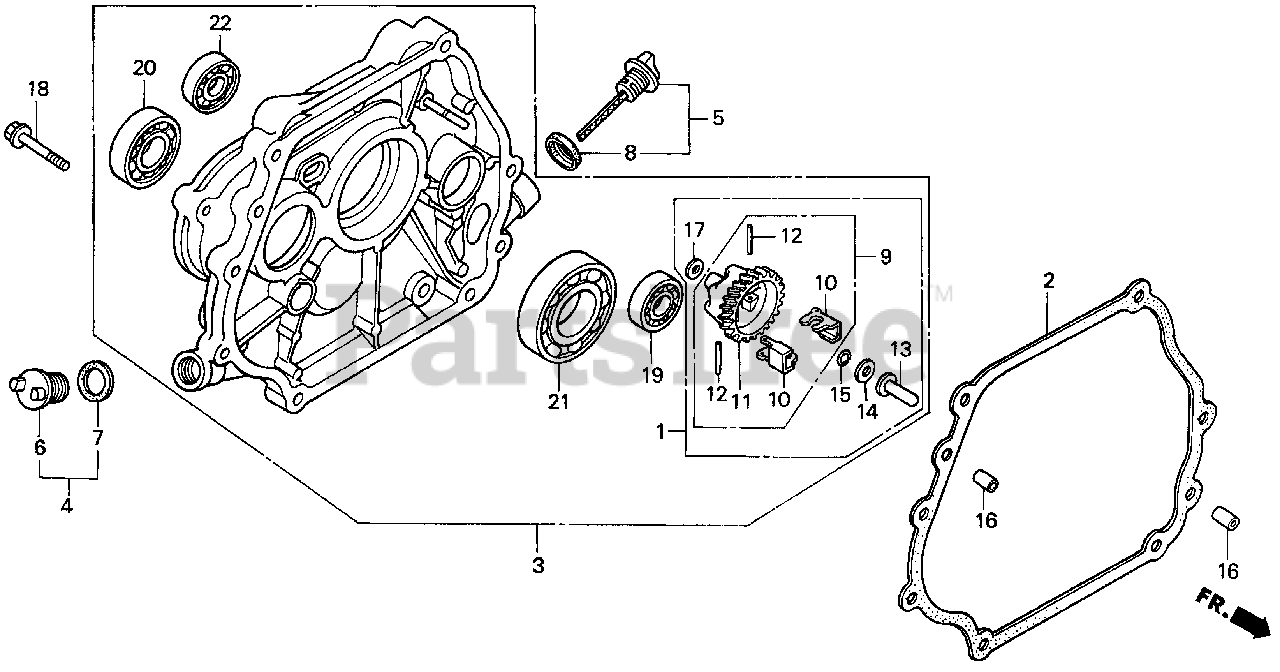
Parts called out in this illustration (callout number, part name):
1	GOVERNOR KIT (BALANCER)
2	GASKET, CASE COVER
3	COVER ASSY., CRANKCASE (H-TYPE)(BALANCER)
4	CAP ASSY., OIL FILLER
5	CAP ASSY., OIL FILLER
6	CAP, OIL FILLER
7	GASKET, OIL FILLER CAP
8	GASKET, OIL FILLER CAP
9	GOVERNOR ASSY. (BALANCER)
10	WEIGHT, GOVERNOR
11	HOLDER, GOVERNOR WEIGHT
12	PIN, GOVERNOR WEIGHT
13	SLIDER, GOVERNOR
14	WASHER (6X16)
15	CLIP, GOVERNOR HOLDER
16	PIN, DOWEL (8X12)
17	WASHER, PLAIN (6MM)
18	BOLT, FLANGE (8X35)
19	BEARING, RADIAL BALL (6202)
20	BEARING, RADIAL BALL (6204)
21	BEARING, RADIAL BALL (6206)
22	BEARING, RADIAL BALL (6302)
